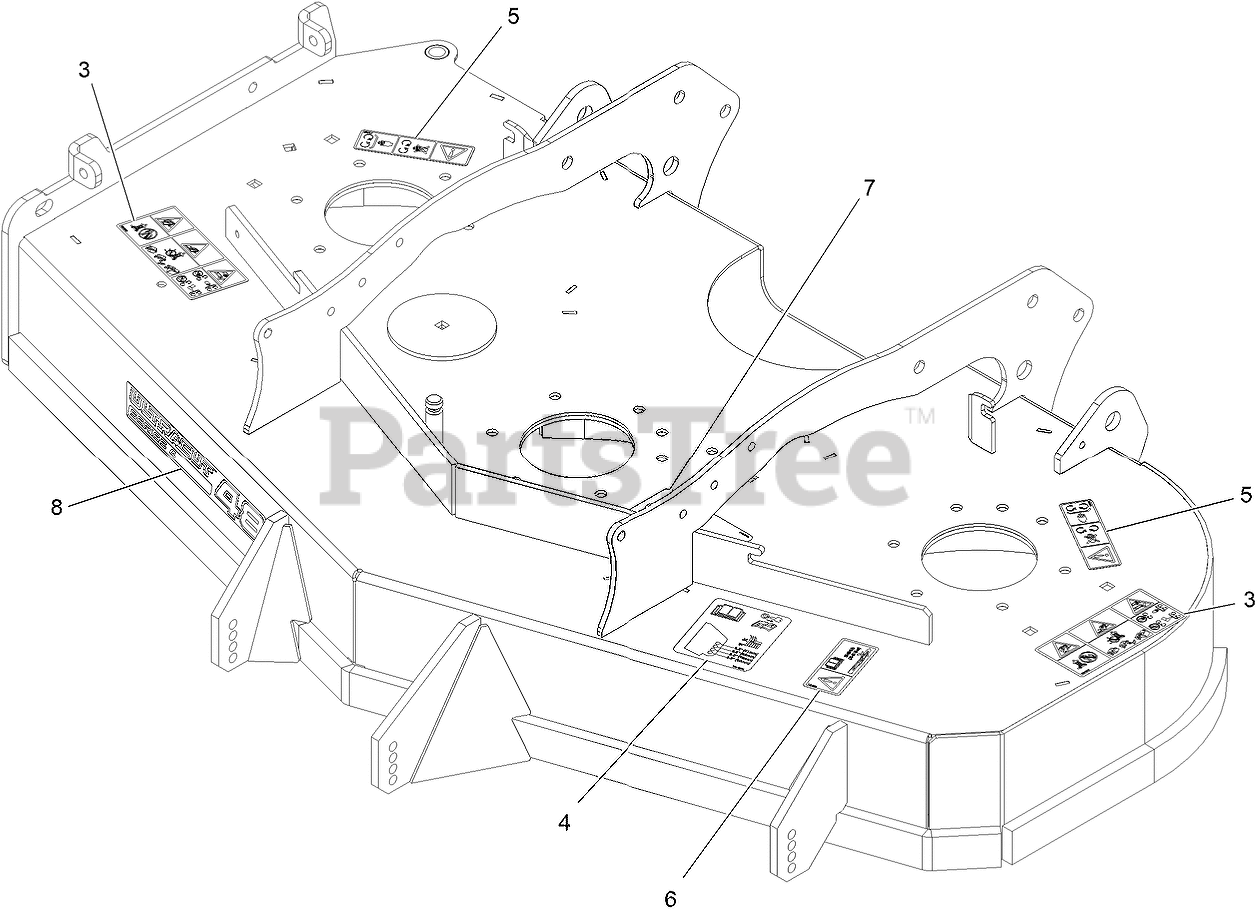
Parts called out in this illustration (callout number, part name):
3	DECAL-WARNING THROWN OBJ
4	DECAL-ROLLER, ANTI-SCALP
5	DECAL-COVER, MISSING
6	DECAL-TORQUE, BOLT
7	DECAL-BELT ROUTING
8	DECAL, 484
